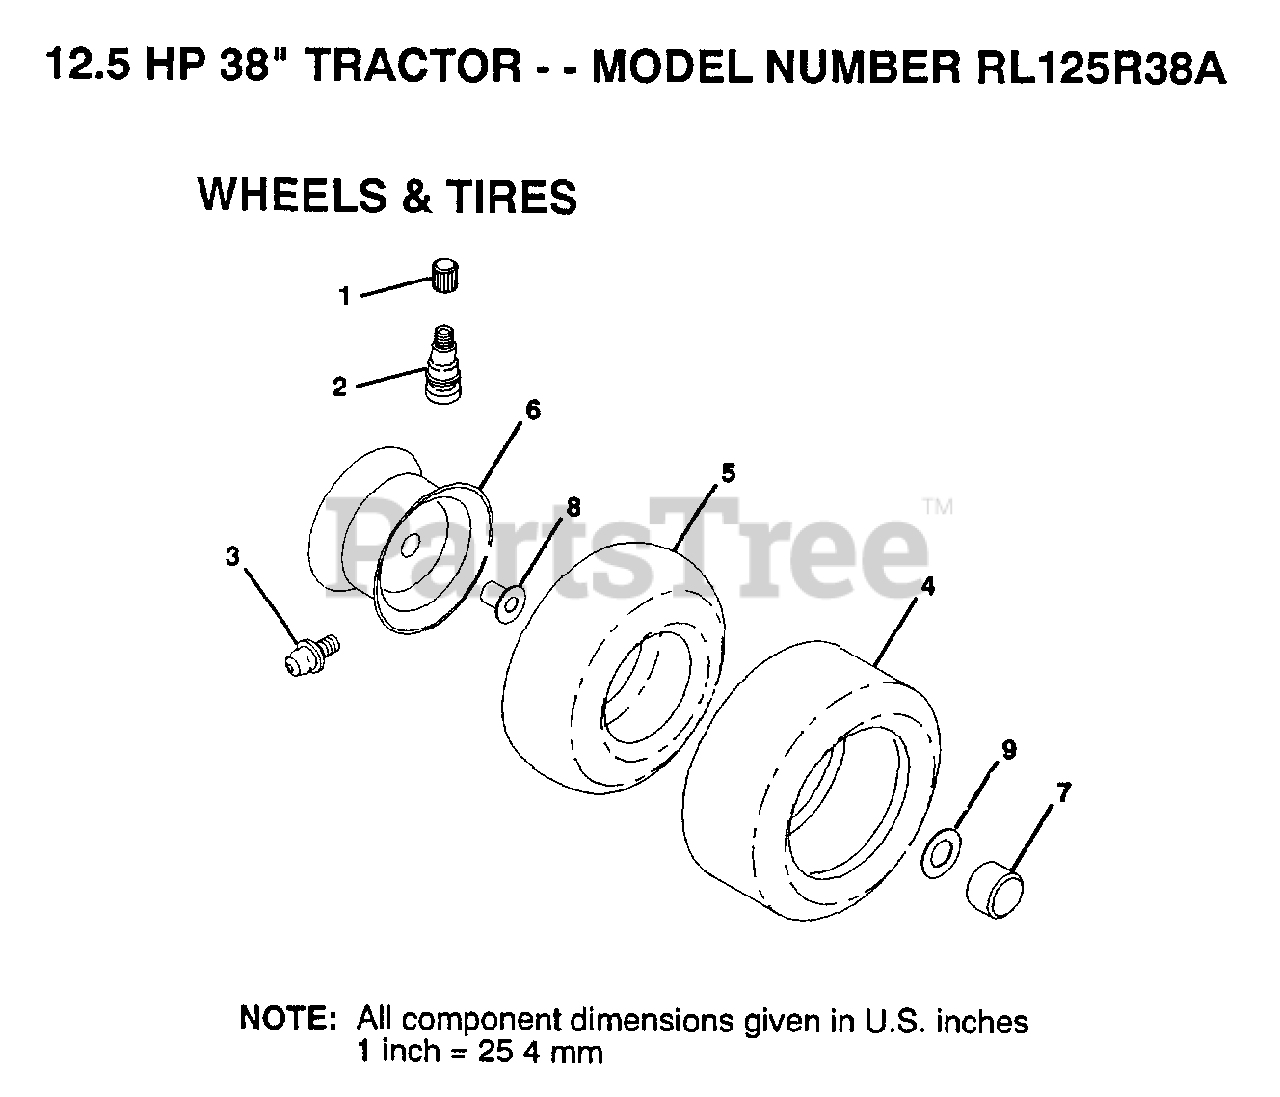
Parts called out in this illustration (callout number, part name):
1	VALVE CAP
2	VALVE STEM LT
3	FITTING LT
5	TUBE.5.3/4.5/6
7	HUB CAP
8	"FLANGE, BEARING"
9	WASHER
